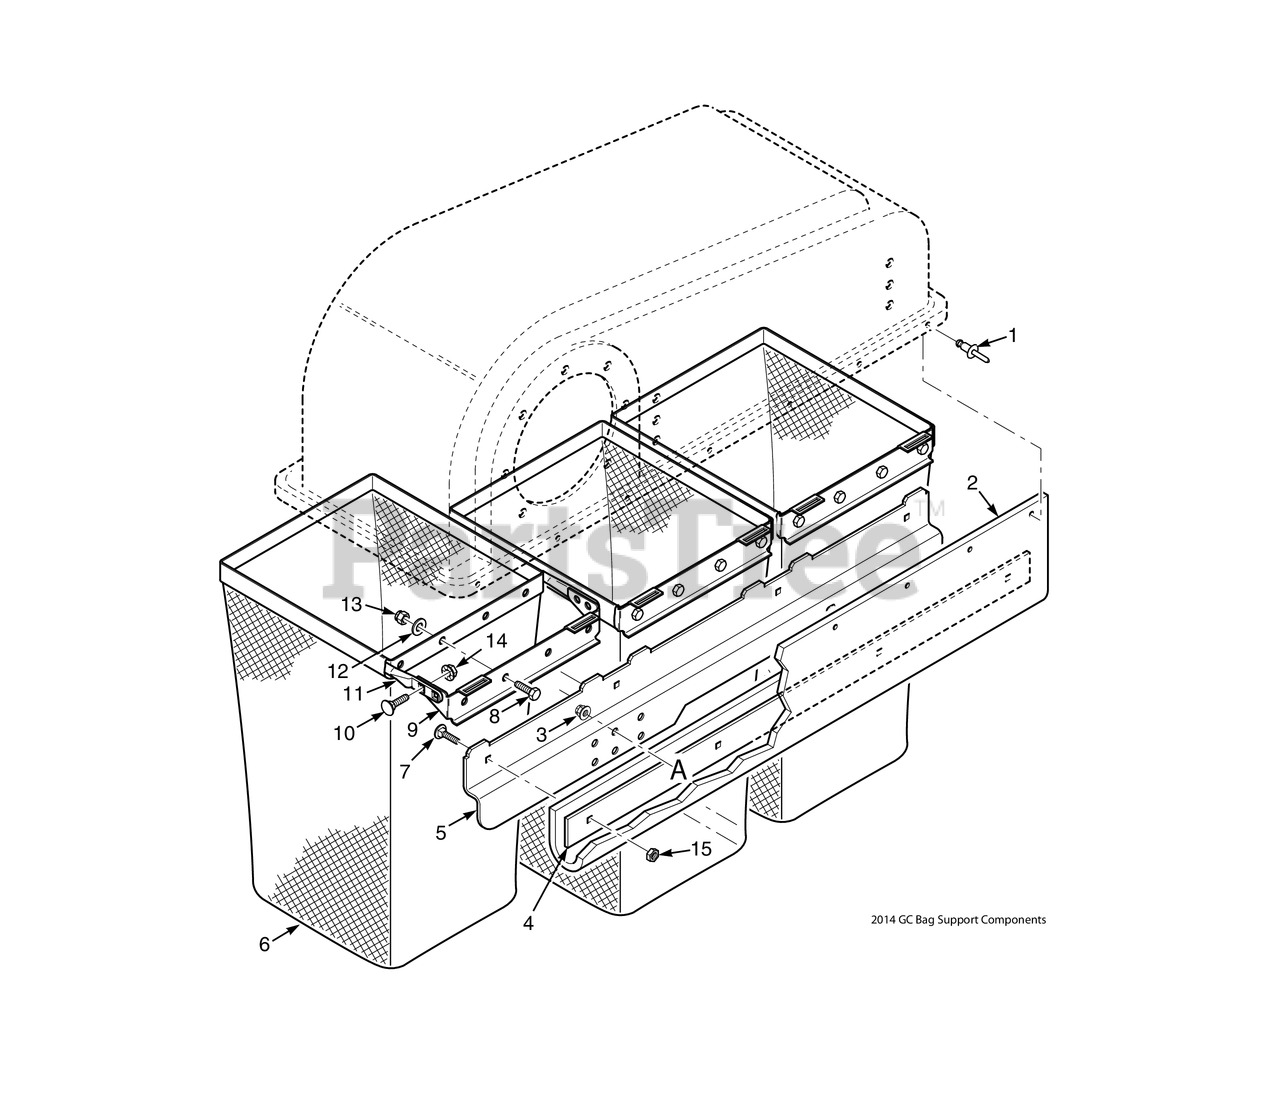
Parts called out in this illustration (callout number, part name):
1	Pop Rivet, 3/16 x .652"
2	Seal, Hood
3	Nut, Flange Elastic Stop Nut, 3/8-16
4	Retainer, Seal
5	Support Weldment, Bag Frame
6	BAG ASSY, GC
7	Serr. Fl. Hex Head CPSCR, 1/4-20 x 3/4"
8	BOLT, SERRATED FLANGE HEX HEAD 5/16-18 X 3/4"
9	Mount, Bag Frame Tube
10	Bolt, 5/16-18 x .75 RHSN Carriage
11	Tube, Bag Support
12	Flatwasher, 5/16-.375 x .875 x .083 (35BV & 37BV-EFI)
13	HEX NUT, ELASTIC STOP LOCK, 5/16-18
14	Nut, Serrated Flange 5/16-18 (Right Front Engine Mounting, Briggs and Kohler Only)
